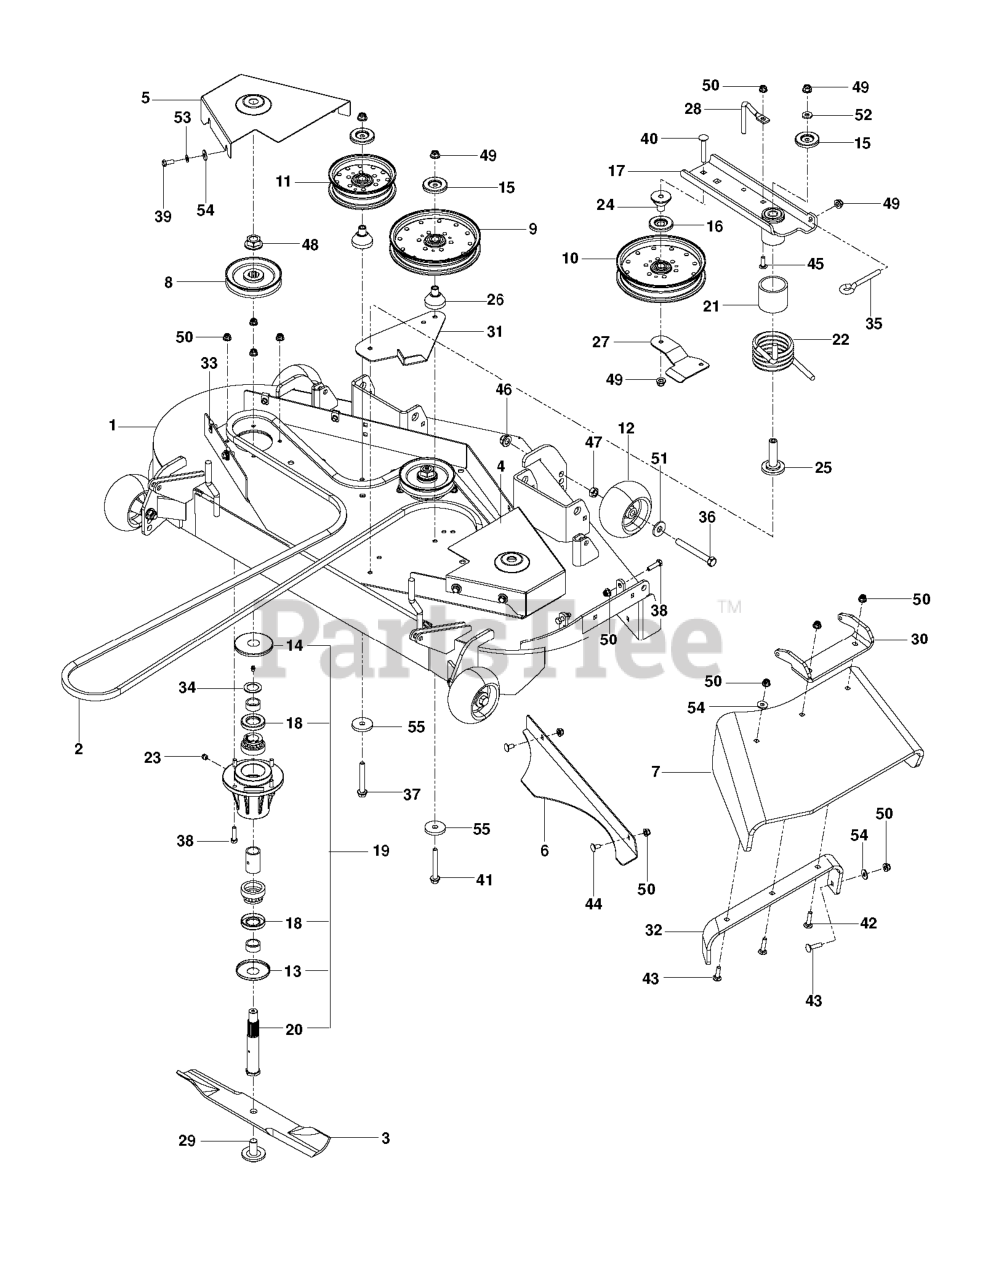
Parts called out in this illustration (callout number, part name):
1	DECK.SVC.W/DECALS.48.PZT.ORNGE
3	BLADE - HEAVY DUTY 16 1/4"
4	BELT SHIELD - R.H. ORANGE
5	BELT SHIELD - L.H. ORANGE
6	CONFINEMENT PLATE 48" BLK
7	CHUTE DISCHARGE 48"
8	PULLEY 42-48
9	PULLEY - IDLER 7"
10	PULLEY - 7" NARROW
11	IDLER PULLEY
12	GAUGE WHEEL
13	BOTTOM DUST CAP
14	TOP DUST CAP
15	DUST SHIELD
16	SHIELD, DUST
17	IDLER.ARM.BLACK
18	SHAFT SEAL
19	HOUSING ASM, 52/61
20	SPACER, IDLER BEARINGS
21	SPACER, IDLER PIVOT
22	SPRING, TORSION, IDLER
23	BEARING, BALL
24	BEARING, IDLER ARM
25	BEARING, IDLER PIVOT
26	BEARING, IDLER STANDOFF
27	BELT.GUIDE.BLACK
28	BELT KEEPER
29	BLADE BOLT/WASHER
30	PIVOT BRACKET - CHUTE
31	BRACKET, SPRING STOP
32	BRKT, REINF - CHUTE 52/61"
33	U-CLIP 5/16-18 NUT RETAINER
34	MACHINE BUSHING
35	EYE BOLT, 3/8 X 4"
36	HCS 1/2-13 X 4 GR 5 ZD
37	HCS 3/8-16 X 4-1/2 GR 8 ZD
38	HCS 5/16C X 1 1/4
39	HCS 5/16C X 3/4
40	CARRIAGE BOLT 3/8-16 X
41	HHFS 3/8-16 X 3 GRD 5 ZD
42	RHSNB 5/16-18 X 1-1/2 GR 5 ZD
43	BOLT, CARRIAGE 5/16X1-1/4
44	CARRIAGE BOLT 5/16C X 5/8"
45	RHSSNB 5/16C X 1.0
46	NUT, 1/2-13 HEX FLG NYLOC ZD
47	NUT 1/2 HEX JAM
48	NUT FLANGE 3/4-16
49	NUT 3/8-16 HEX FLG NYLOC ZD
50	5/16-18 NYLOC FLANGE NUT
51	WASH USS FLAT 1/2
52	WASHER, 3/8 THICK
53	WASH 5/16 DISC SPRING ZD
54	WASHER 5/16 FLAT
55	SPINDLE WASHER
56	PLUG-VENTED
